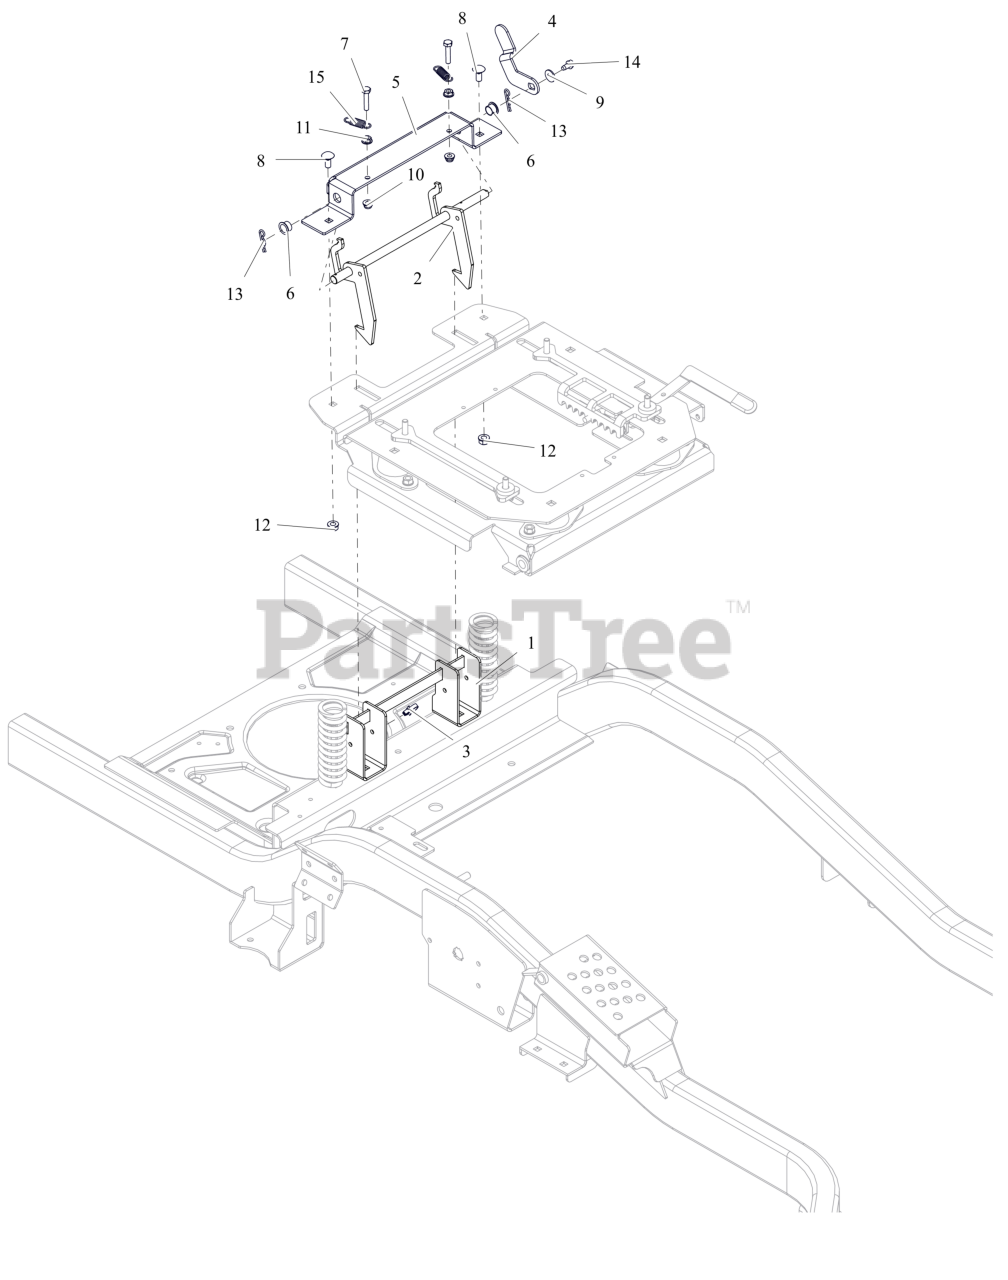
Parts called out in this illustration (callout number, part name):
1	WLDMT, LATCH RECEIVER
2	WLDMT, SEAT
3	ROUTING CLIP (1/2" ID)
4	LEVER, SEAT
5	BRKT, SEAT
6	BUSHING, POLYLINER-.50 SPLIT
7	BLT, HEX .25-20X1.25 G5 ZCC
8	BLT,RHSN .31-18X.75 G5 ZCC
9	WSHR, FLT .312X.734X.065 ZCC
10	NUT,NYL-FLG .25-20 GF ZCC
11	NUT-SPNLK-FLG .25-20 ZC120
12	NUT,LK-CTR-FLG .31-18 GF ZCC
13	PIN, HAIR-INT .08X.38X1.42 ZCC
14	SCR-TAP .25-20X.50 HWH ZCC
15	SG-TENS .063X.44X1.56
